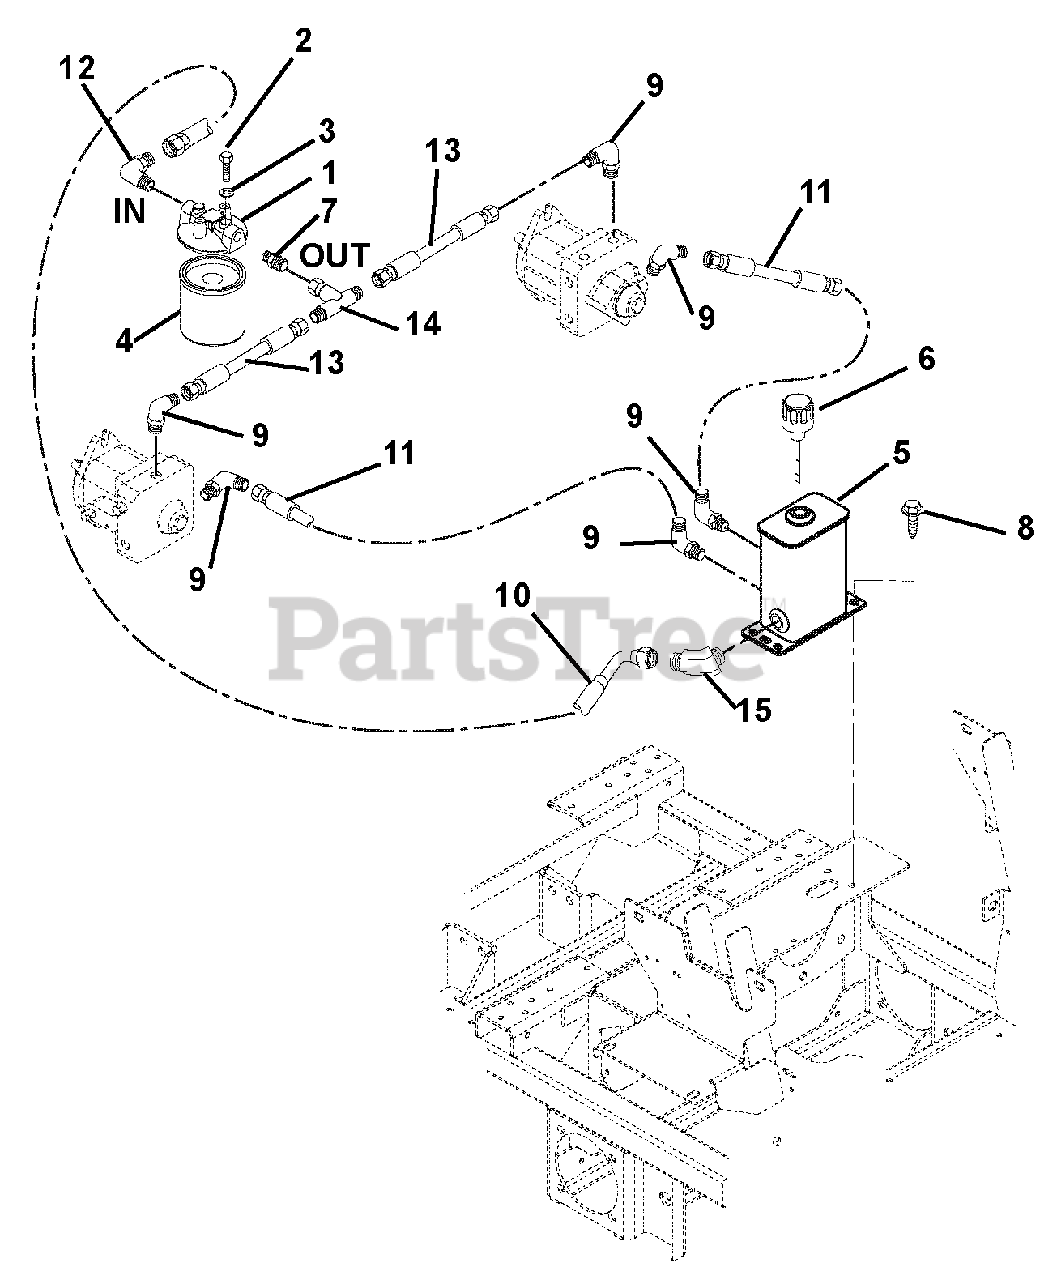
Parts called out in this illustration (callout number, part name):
1	Filter Housing
2	Bolt-Hex .25-20 x .50 Grade 5
3	Washer-Locking .25 x .062
4	Filter Element
5	Body, Hydraulic Tank
6	Breather, Dipstick
7	Fitting, Hydraulic, Straight Steel
8	Screw-Tapping .38-16 x .75 Hex Washer Head
9	Fitting, Hydraulic, 90 Degree Elbow
10	Hose-Hydraulic Valve to Tank
11	Hose, Hydraulic, 10-inch
12	Fitting, Hydraulic, 90 Degree Elbow
13	Hose, Hydraulic .50, 5-Inch
14	Fitting, Hydraulic Tee
15	Fitting, Hydraulic .45 Degree Elbow
